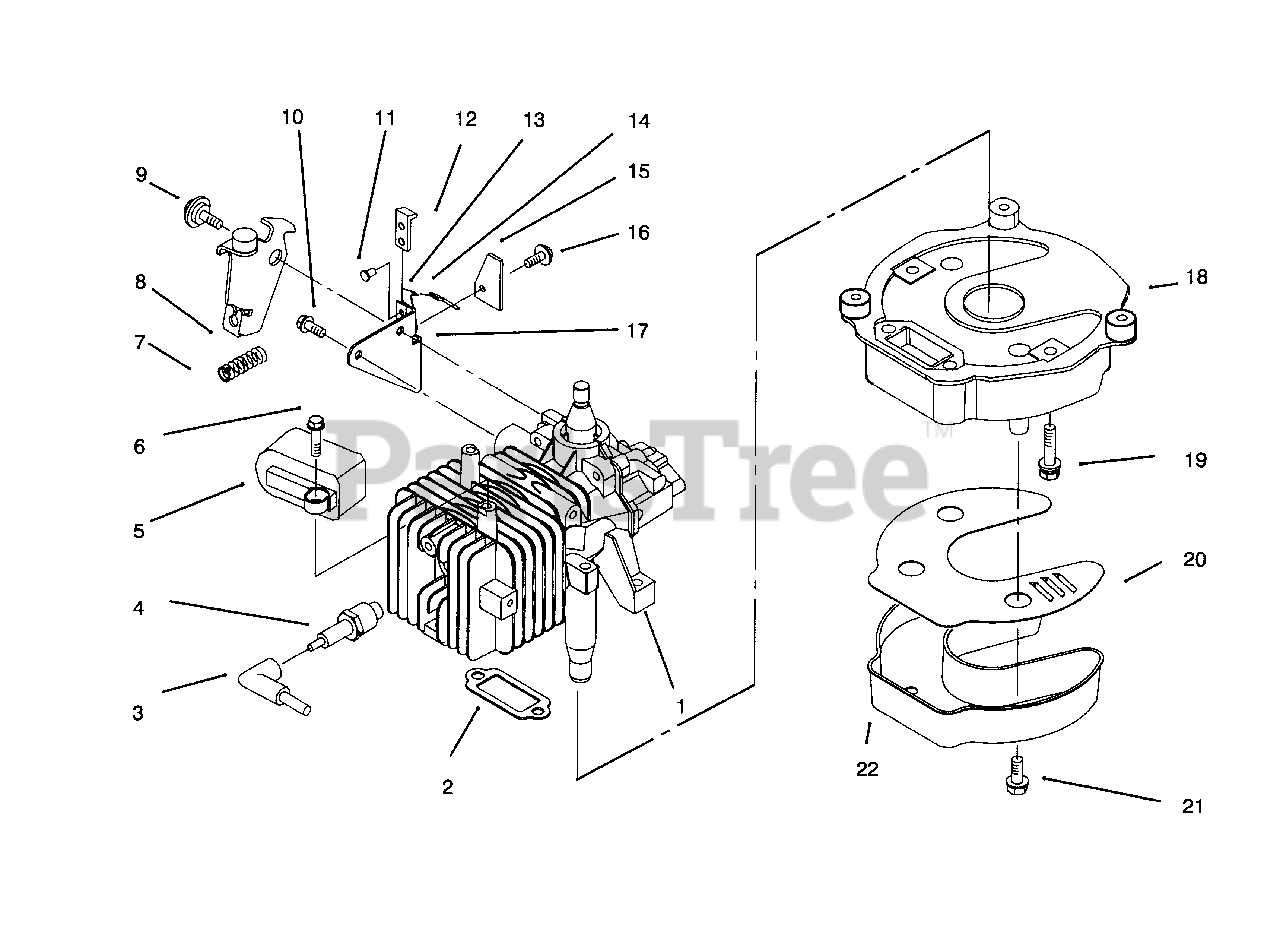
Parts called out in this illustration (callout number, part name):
1	Short Block
2	Gasket-Exhaust
3	Wire-Plug (Includes)
4	Plug-Spark
5	CD Ignition (Incl. Ref. #3)
6	Screw-Hex. Washer Hd.
7	Spring-Compression
8	Brake Plate Assembly
9	Screw-Shoulder
10	Screw
11	Rivet-Plastic
12	Strap-Insulation
13	Strap-Ground
14	Wire-Brake Switch Lead
15	Stop-Ground Strap
16	Screw-Thread Forming
17	Mounting Plate Assembly
18	Plate-Muffler
20	Baffle
22	Cover-Muffler
